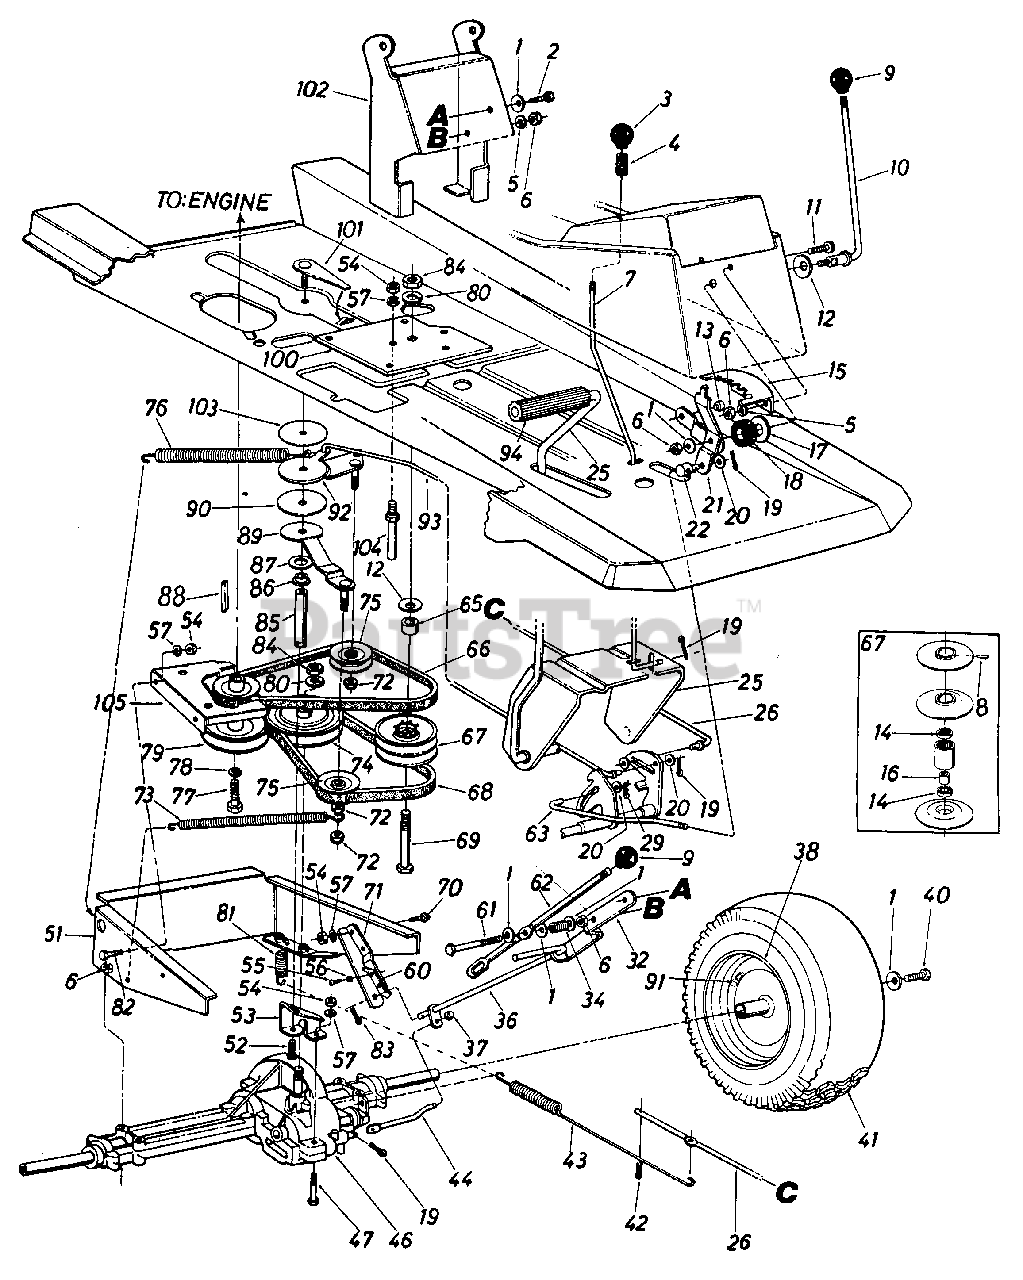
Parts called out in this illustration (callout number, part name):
1	WASHER-BELL .337 X .867 X .057
2	SCREW-HEX WASH HD
4	SPRING-COMPRESSION
5	WASHER-LOCK-5/16
6	NUT-HEX 5/16-18
7	ROD-BRAKE LOCK
8	PIN-SPRING SPIR 5/32 X .62
9	KNOB-BALL 1-3/8" DIA.
10	LEVER-SPEED CONTROL
11	SCREW-TRUSS MACH 5/16-18 X .75
12	WASHER-BELL .505 ID X 1.00 OD
14	BEARING-BALL
15	BRACKET-INDEX
17	WASHER-SPEC 503 X 1.56 X .036
18	WASHER-RUBBER
19	PIN-COTTER-1/8 DIA X 1.00
20	WASHER-FL (#46041)
21	BRACKET ASSY-SP CONT
22	FERRULE
25	PEDAL ASSY-BRAKE
26	ROD-BRAKE
29	PIN-INTERN COT-5/16 DIA
32	BRACKET-SHIFT LEVER
34	SPRING
36	LEVER ASSY-SHIFT
38	WHEEL RIM-RR 6.0 X 4.50
40	SCREW-CAP LOCK 5/16-24 X .75
41	WHEEL ASSY W/TIRE-15.0X6.0 TURF TD
42	Cotter Pin, 1/8 X 1.25
43	SPRING-EXTENSION
44	ROD-SHIFT
46	TRANSAXLE-1 SP
47	SCREW-HEX 1/4-20 X 1.75
53	BRACKET-TORQUE ROD
54	NUT-HEX 1/4-20
55	SCREW-C SINK #8X.50
57	LOCK WASHER 1/4 DIA
60	SPRING-SWITCH
61	SCREW-HEX 5/16-18 X 2.25
62	KIT-SHIFT LEVER
63	LINK-SPEED CONTROL
66	BELT-5LX35.25
67	PULLEY ASSY-VAR SP
68	BELT-V 5/8 X 38
69	SCREW-HEX 1/2-13 X 4.0
70	SCREW-HEX 1/4-20 C .62
71	SUPPORT-SHIFT LEVER
72	NUT-HEX INS L-3/8-24
73	SPRING-EXTENSION
75	PULLEY-V-BELT IDLER
76	SPRING-EXTENSION
77	SCREW-HEX 7/16-20 X 1.00
78	WASHER-LOCK-7/16
80	WASHER-LOCK-1/2
81	SPRING-EXTENSION
82	SCREW-HEX B-TAP 1/4 X .38
83	PIN-COTTER-3/32 DIA X 1.00
84	NUT-HEX 1/2-13
85	ROD-TORQUE
86	BEARING-FLANGE
87	WASHER-FL-.640ID X 1.24OD X .06HDN
88	KEY-SQ 1/4 X 2.00
89	BRACKET ASSY-IDLER
90	WASHER-THRUST
91	VALVE-TUBELESS AIR
92	BRACKET ASSY-IDLER
93	ROD-CLUTCH
94	PAD-FOOT
100	BRACKET-VAR SP MTG
103	WASHER-THRUST .038ID X 3.5 X .015
104	ROD-BELT GUARD
105	GUARD-ENG BELT-UPR
